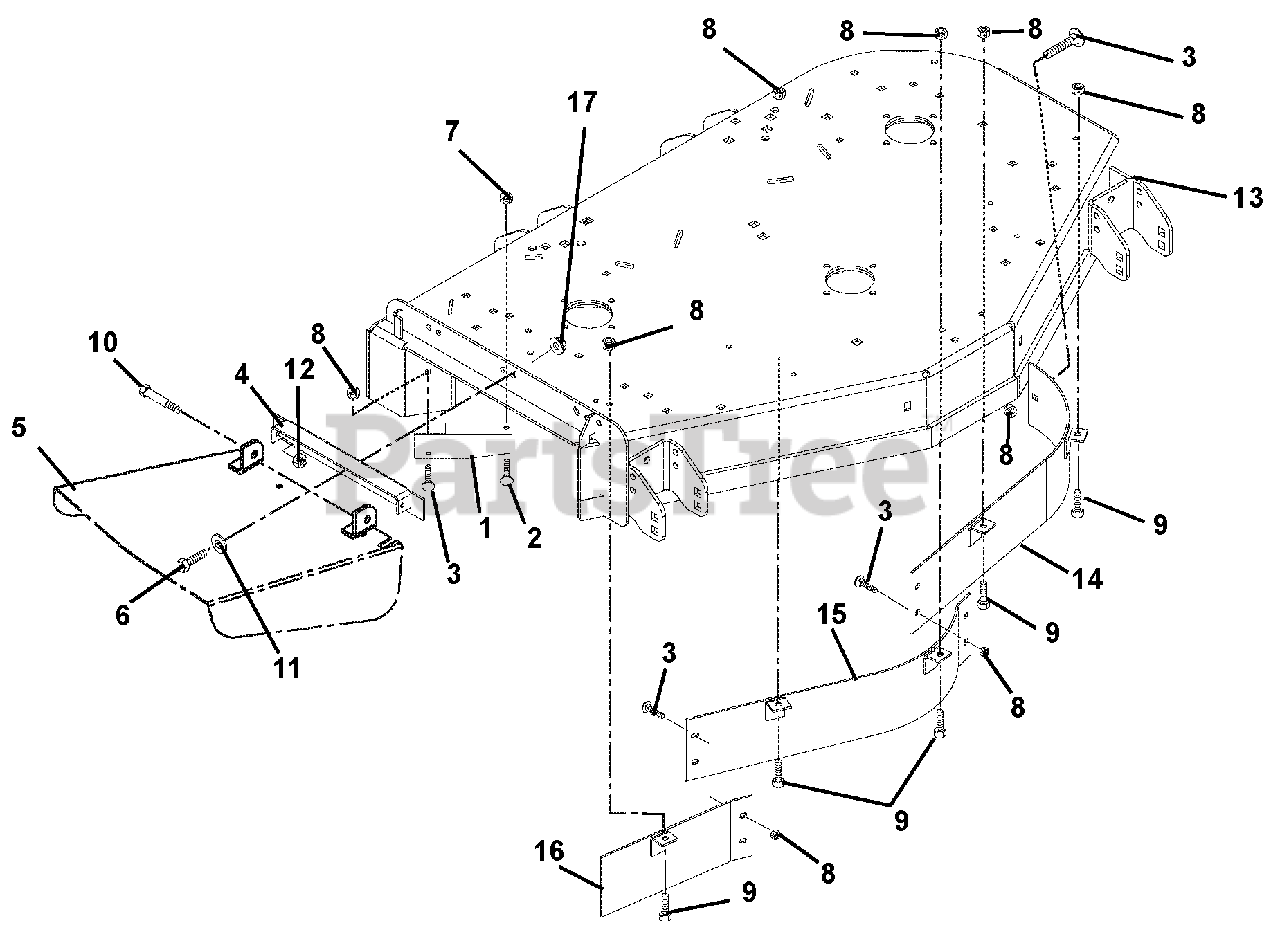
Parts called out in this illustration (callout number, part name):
1	Deflector- 72 in. (086, 091, 107)
2	Bolt-Round Head Square Neck .38-16 x .75 Grade 5
3	Bolt-Round Head Square Neck .31-18 x .75 Grade 5
4	Weldment, Discharge Chute Bracket (045, 052, 066, 071, 084, 087, 102, 103, 104)
5	Chute-Discharge (045, 052, 066, 071, 084, 087, 102, 103, 104)
6	Bolt-Hex .38-16 x 1.00 Grade 5
7	Nut-Locking-Top-Flange .38-16
8	Nut, Locking-Top-Flange .31-18
9	Bolt, Hex .31-18 x .75 Grade 5
10	Bolt, Shoulder .38-16 x .50 Socket Head
11	Washer, Flat Steel .38 x .875 x .083 (045, 052, 066, 071, 084, 087, 102, 103, 104)
12	Nut, Locking-Center .38-16
13	Weldment, 52 in. Mower Deck (045, 052, 066, 071, 084, 087, 102, 103, 104)
14	Weldment, Upper Baffle Left 52 in. (045, 052, 066, 071, 084, 087, 102, 103, 104)
15	Weldment, Baffle, Center Front 52 in. (045, 052, 066, 071, 084, 087, 102, 103, 104)
16	Weldment, Baffle, Right Front 52 in. (045, 052, 066, 071, 084, 087, 102, 103, 104)
17	Nut, Flange .375-16
